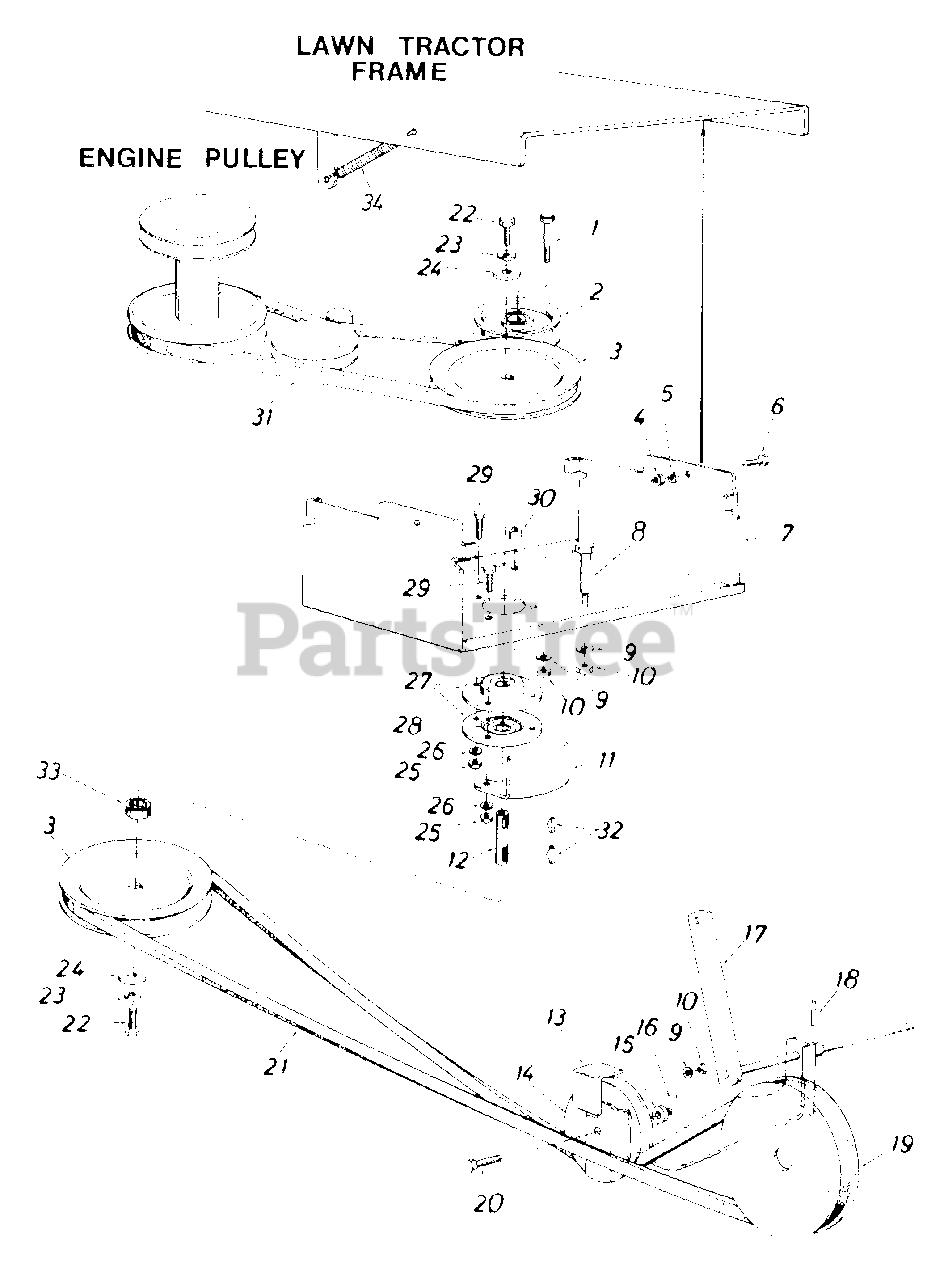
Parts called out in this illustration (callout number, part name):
1	Hex Bolt 3/8-16 x 2.00" Lg.
2	Fl.-Idler w/Flanges 3-3/4" O.D.
3	5/8" "V" -Pulley .790" I.D. x .650" O.D.
4	Hex Nut 3/8-24 Thd.
5	L.-Wash. 3/8" I.D. Heavy Duty
6	Hex Bolt 3/8-24 x .88" Lg.
9	L.-Wash. 3/8" I.D.
10	Hex Nut 3/8-16 Thd.
13	Belt Separator Plate
14	Fl.-Idler w/Flanges 3.25"
15	Fl.-Wash. .406" I.D. x 1.25"
18	Spring Pin Roll 3/16" Dia.
19	5/8" V-pulley 1.50" I.D. x 6.50" O.D.
20	Hex Bolt 3/8-16 x 1.75" Lg.
21	"V"-Belt
22	Hex Bolt 5/16-18 x .88" Lg. Spec.
23	L.-Wash 5/16" I.D.
24	Fl.-Wash. .344" I.D. x 1.125"
25	Hex Nut 5/16-18 Thd.
26	L.-Wash. 5/16" I.D.
27	Bearing Housing 1.85" I.D.
28	Ball Bearing 1.85" O.D.
29	Hex Sems Bolt 5/16-18 x .75"
30	Spacer
31	Belt 1/2" Wide x 52" Long
32	Hi-Pro Key 3/16" x 5/8"
33	Spacer.66" I.D. x 1.0" O.D.
34	Extension Spring
